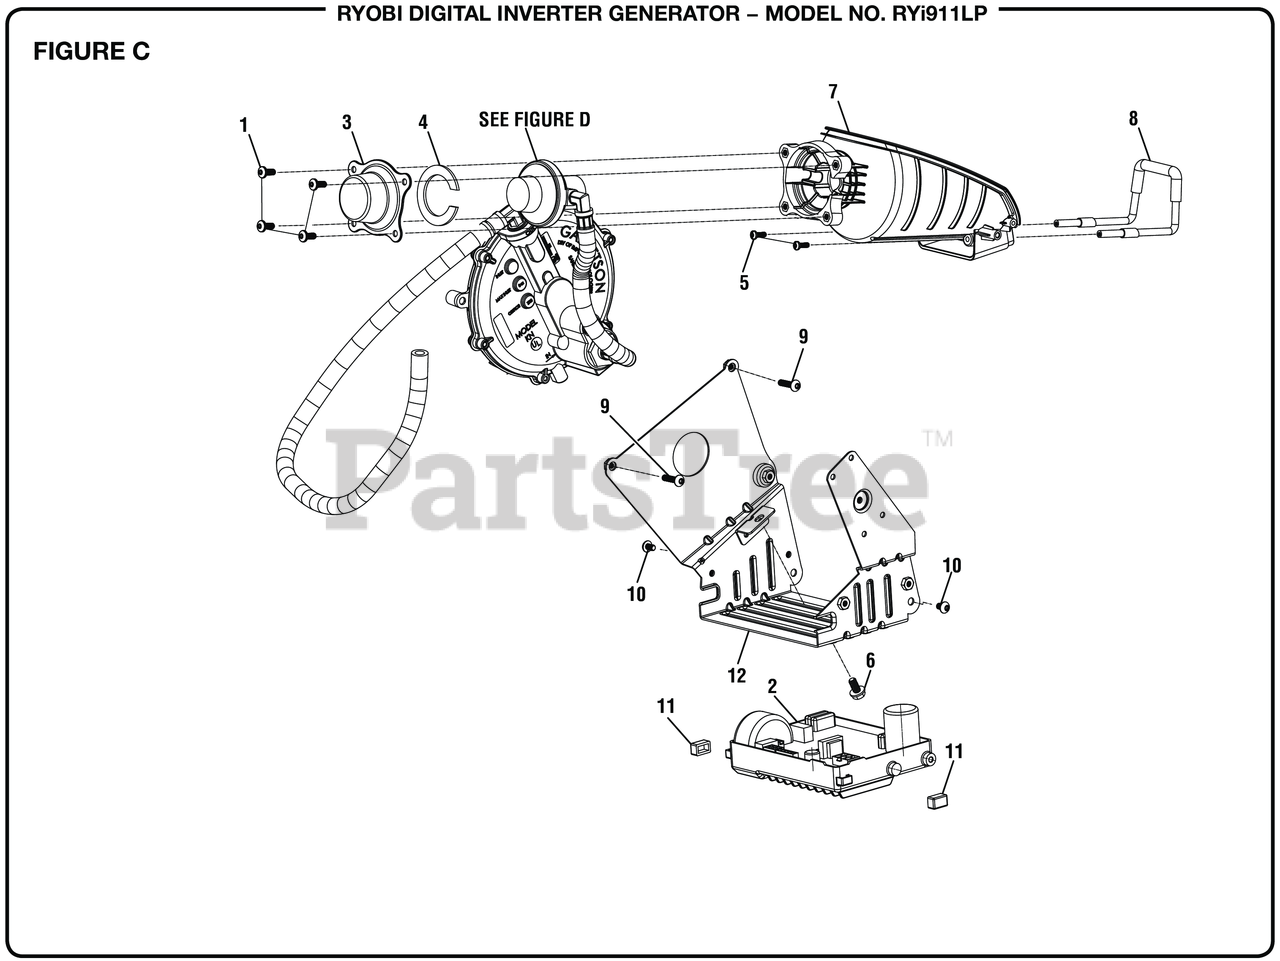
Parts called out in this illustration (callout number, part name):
1	Screw (M5 x 12 mm, T-25 Torx Washer Pan Hd.)
2	Inverter Module (700W)
3	Metal Cover
4	Rubber Pad
5	Screw (M4 x 12 mm, T-20 Torx Washer Pan Hd.)
6	Bolt (1/4 in. x 20-1/2 in., Flanged Hex Hd.)
7	1LP Tank Assembly
8	Metal Tube
9	Screw (M5 x 22 mm, T-25 Torx Pan Hd.)
10	Screw (M5 x 8 mm, T-25 Torx Pan Hd.)
11	Rubber Support
